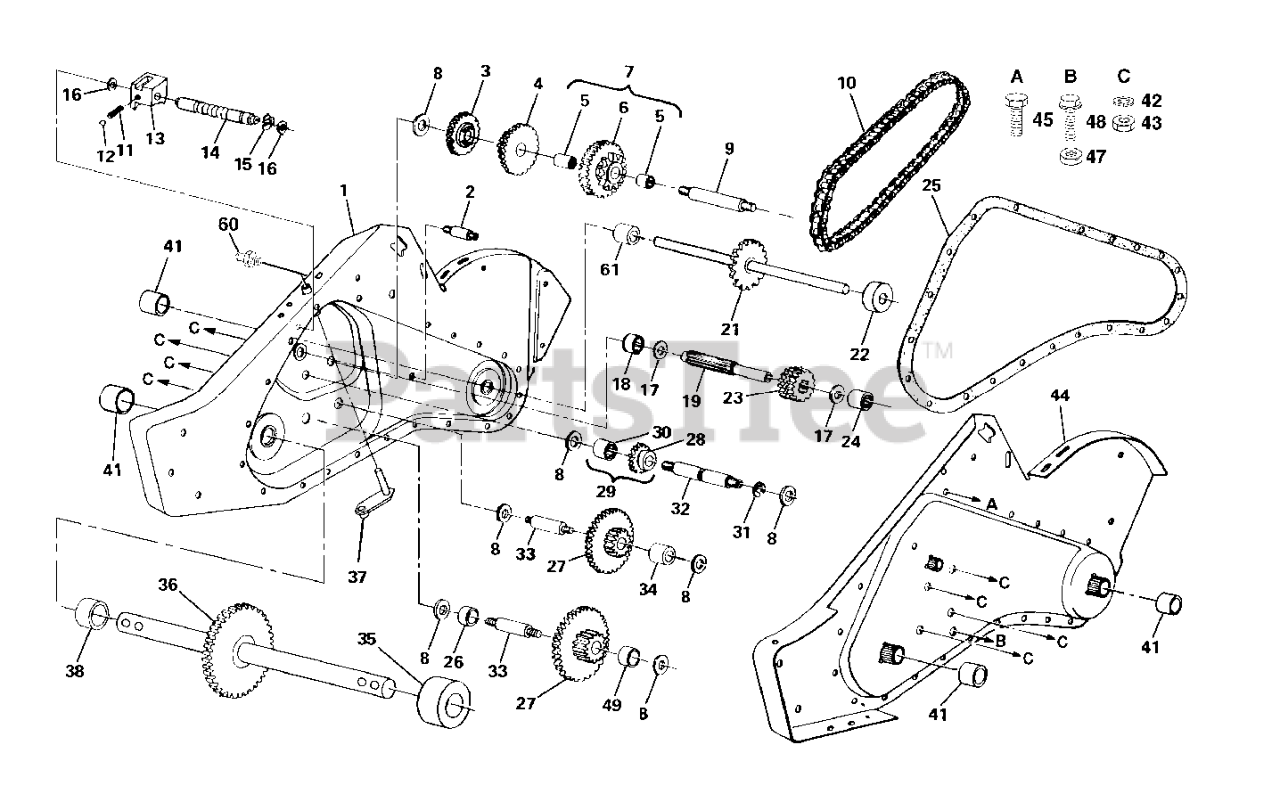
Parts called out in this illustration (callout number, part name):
1	GEARCASE ASM.RH.W/BEARING 2002
2	SPACER.GEARCASE
3	GEAR.REVERSE.8HP
5	BEARING.NEEDLE.CRT
6	SPROCKET ASMBLY, TINE
7	SPROCKET ASMBLY W/BEARINGS
9	SHAFT.REDUCTION.TILLER
10	CHAIN.ROLLER.TILLER
11	SPRING-SHIFT CRT
12	STEEL BALL KIT
13	SHIFT FORK TI
14	SHAFT.SHIFT.1.00 PINION
16	WASHER, SEAL (2 2)
17	THRUST WASHER
18	BEARING TI
19	SHAFT INPUT
22	SPACER 1.008X1-3/4X.645
23	GEAR.PINION
24	NEEDLE BRNG LT
27	GEAR, CLUSTER CRT
28	REVERSE GEAR
29	GEAR ASMBLY, REVERSE IDLER
30	NEEDLE BEARING TI
32	SHAFT, REVERSE IDLER
33	SHAFT, REDUCTION
34	SPACER.765 X 1.12 X .380.
35	SPACER, GROUND DRIVE RH
36	SHAFT ASSY CRT
37	BRACKET ASM.SHIFT.CRT
38	SPACER, GROUND DRIVE
41	SEAL ASM, OIL
42	LOCKWASHER
43	NUT.ASF.HEX.7/16
44	GEARCASE ASM.LH.W/BEARING 2002
45	BOLT.5/16HEX.WHS.HD
47	NUT
48	SCREW 5/16-18X4
60	FITTING.GREASE.TAPERED
